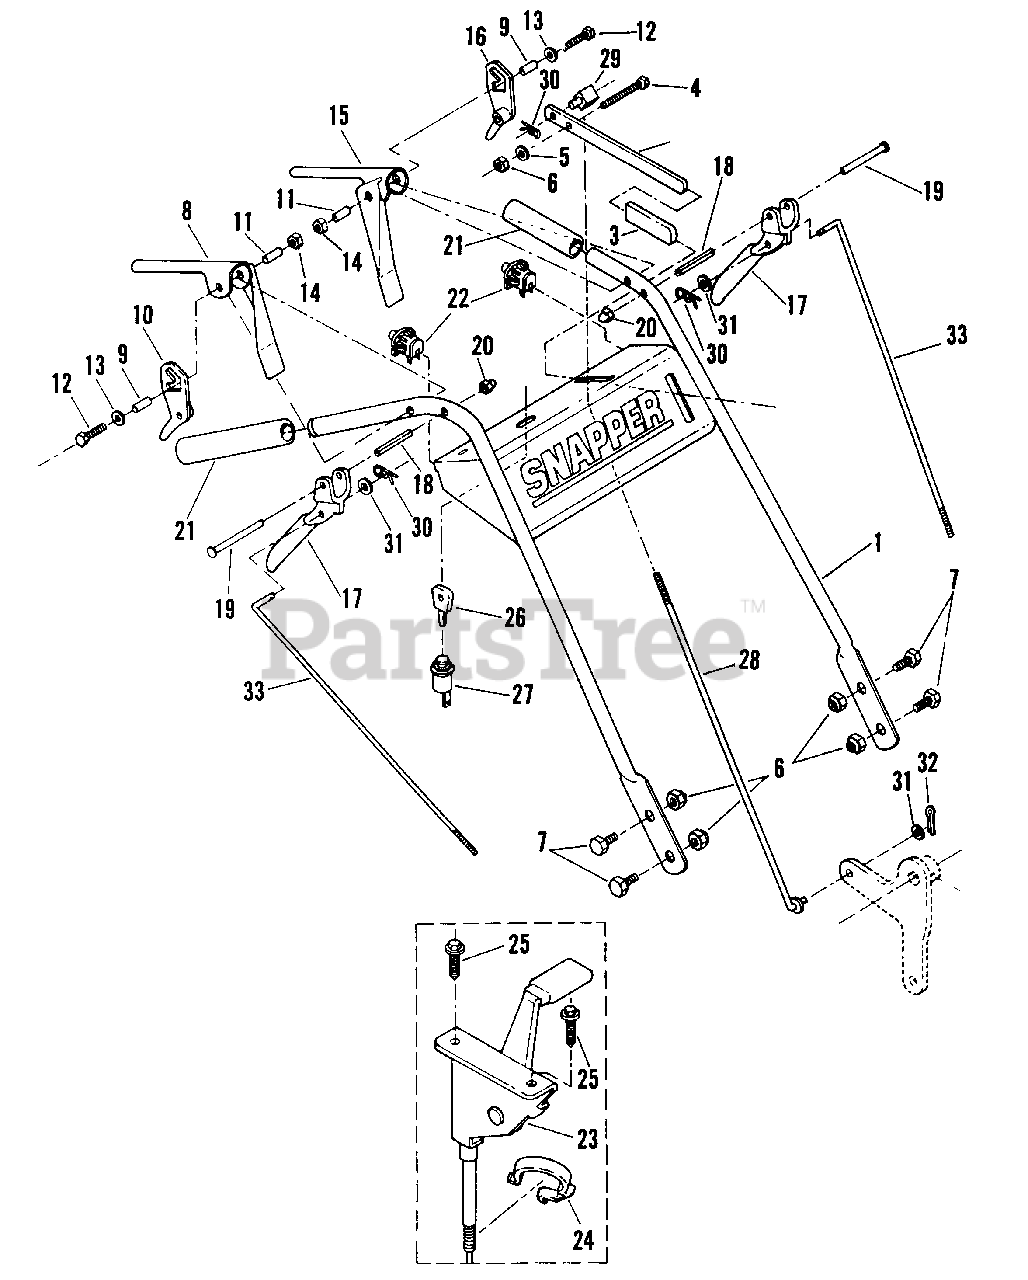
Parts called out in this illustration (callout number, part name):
1	HANDLE, Pistol Grip
3	GRIP, Lever
4	BOLT, 3/8-16 x 3" Hex
5	WASHER, 3/8" Flat
6	NUT, 3/8-16 Nyloc
7	BOLT, 3/8-16 x 1" Hex Grade 5
8	OPC, Pistol Grip R.H.
9	SPACER, OPC
10	LATCH, R.N.
11	SPACER, Brake
12	SCREW, 1/4-20 x 2-3/4" Hex Cap
13	WASHER, 1/4" Flat
14	NUT, 1/4-20 Hex Lock
15	OPC, Pistol Grip L.H.
16	LATCH, L.H.
17	LEVER, Drive (with grip)
18	P IN, Roll
19	PIN, 3/16 x 1-3/4" Clevis
20	NUT, 3/16" Push
21	GRIP, Handle
22	SWITCH, Seat
23	CONTROL, Throttle
24	CLIP, Throttle
25	SCREW, #10-24 x 1/2" Hex Washer Self-Tap (Torx)
26	KEY, Switch (With Cover)
27	SWITCH, ON-OFF
28	ROD, Blade Clutch (Pistol Grip Handle)
29	SWIVEL
30	PIN, #13
31	WASHER, 3/8" Flat
32	PIN, 3/32 x 1" Cotter
33	ROD, Traction
